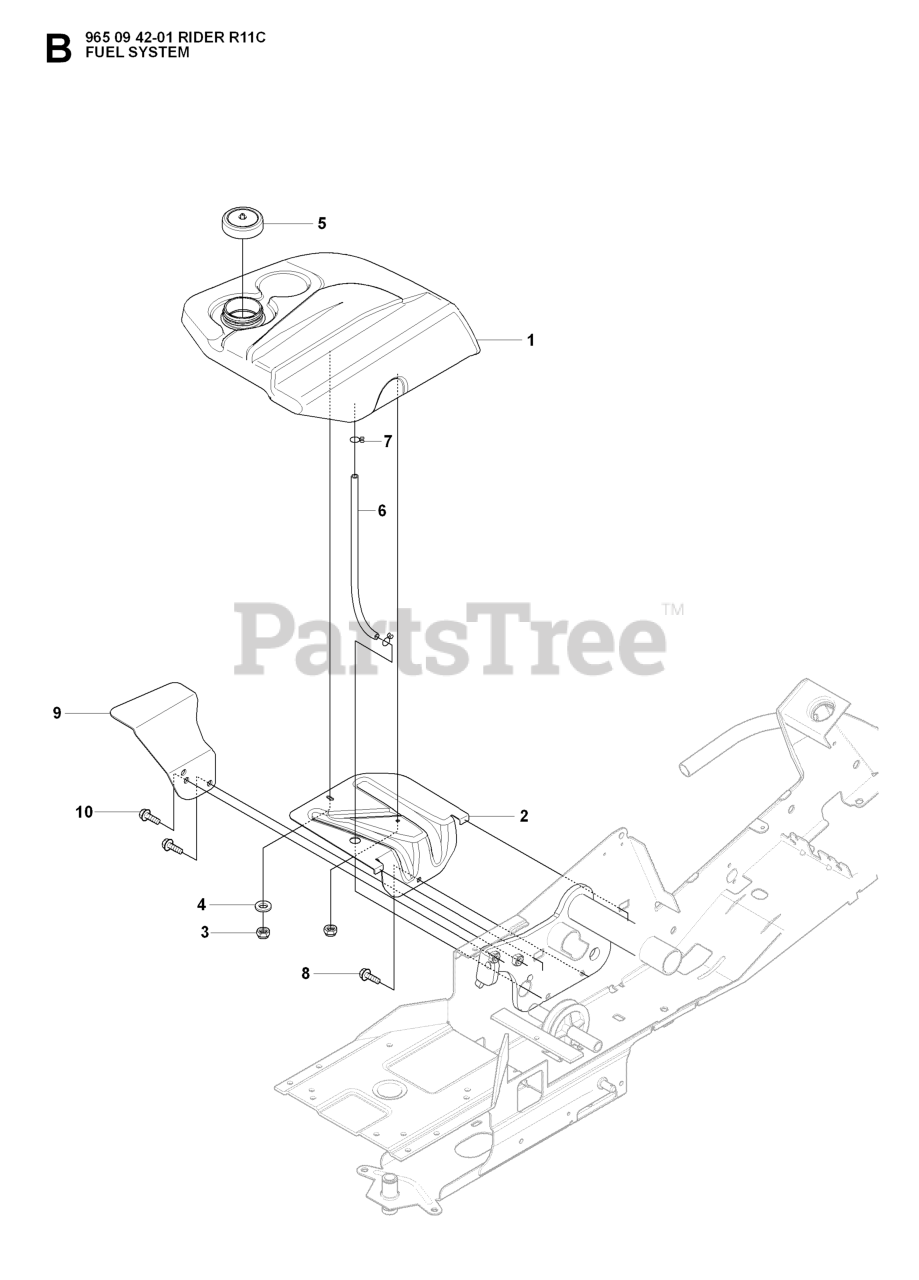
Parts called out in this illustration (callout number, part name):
3	LOCKNUT M6
4	WASHER
10	Screw M10x25
